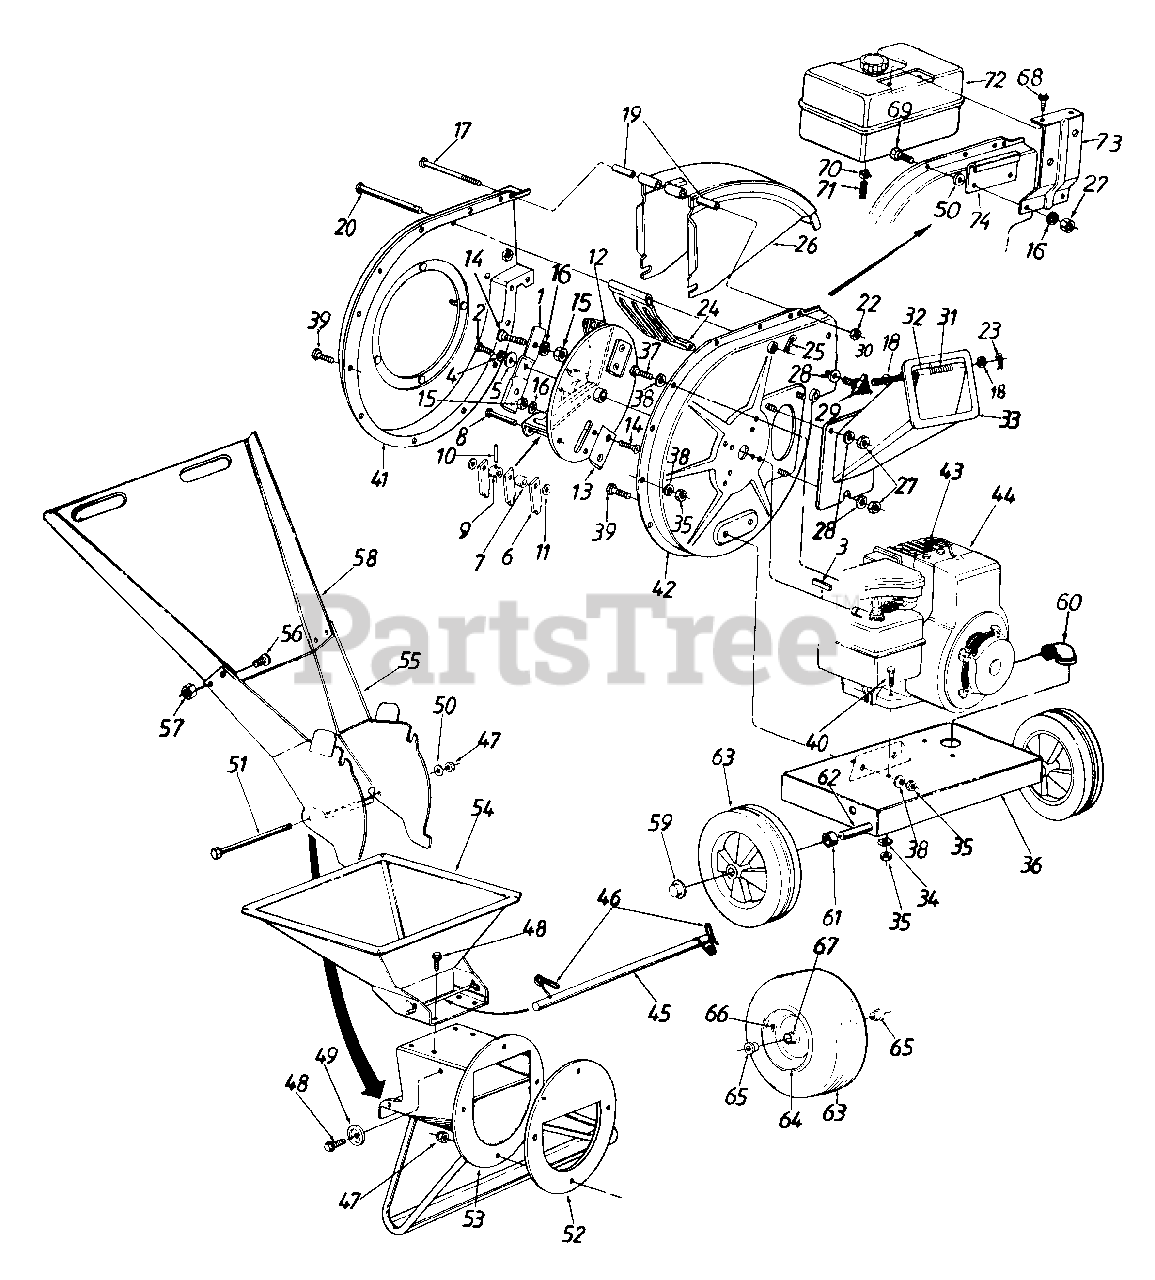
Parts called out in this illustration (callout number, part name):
1	Blade
2	Hex Patch Bolt 3/8-24 x 2" Lg.
3	Sq. Key 1/4 x 2.0" Lg.
4	L-Wash. 3/8" I.D. H.D.
5	Fl-Wash. .406" I.D. x 1.25" O.D. Hdn.
6	Flail
7	Flail Spacer
8	Clevis Pin .496" Dia.
9	Flail Spacer w/.160" Dia. Hole
10	Spring Roll Pin 1.12" Lg.
11	Fl-Wash. .531" I.D. x .94" O.D.
12	Impeller Ass'y. Comp.
13	Chipper Blade
14	Flat Hd. Scr. 5/16-24 x .75" Lg.
15	Hex Top L-Nut 5/16-24 (Gr. 5)
16	L-Wash. 5/16" I.D.
17	Hex Bolt 1/4-20 x 3.75" Lg.
18	Fl-Wash. .281" I.D. x .5" O.D.
19	Chute Hinge Spacer 1.66" Lg.
20	Clevis Pin .5" Dia. x 4.62" Lg.
22	Hex Ctr. L-Nut 1/4-20 Thd.
23	Cotter Pin 3/32" x 5/8"
25	Internal Cotter Pin 3/8" Dia.
27	Hex Nut 5/16-18 Thd. (Gr. 5)
28	Bell-Wash. .345" I.D. x .88"
29	Hand Knob
30	Chipper Door Rod
31	Torsion Spring 1.14" Lg.
35	Hex Nut 5/16-18 Thd. (Gr. 5)
38	L-Wash. 5/16" I.D.
39	Hex Bolt 5/16-18 x .75" Lg. (Gr. 5)
40	Hex Bolt 5/16-18 x 1 5" Lg. (5 H.P. & 8 H.P. Tec.)
40	Hex Bolt 5/16-18 x 1 75" Lg.(8 H.P.)
44	Engine
45	Release Bar
46	Torsion Spring 1.06" Lg.
47	Elastic Lock Nut 5/16-18 Thd.
48	Hex Wash. Hd. Self-Tap Scr. 5/16-18 x 75" Lg.
49	Stop Washer
50	Fl-Wash. 5/16" I.D.
51	Hex Bolt 5/16-18 x 8.38" Lg.
57	Hex L-Nut 1/4-20 Thd.
60	Drain Elbow (5 HP. B&S)
61	Spacer 64" I.D. x 38" Lg.
62	Shredder Axle
63	Wheel Ass'y Comp (Plastic - 10 x 25)
64	Rim Only
65	Flange Bearing 632" I.D.
66	Air Valve
67	Grease Fltting
68	Hex Hi-Low Scr. 1/4 x 75"
69	Hex Bolt 5/16-18 x 88" Lg.
70	Hose Clamp
71	Fuel Line - 7 in.
72	Fuel Tank Ass'y Comp
